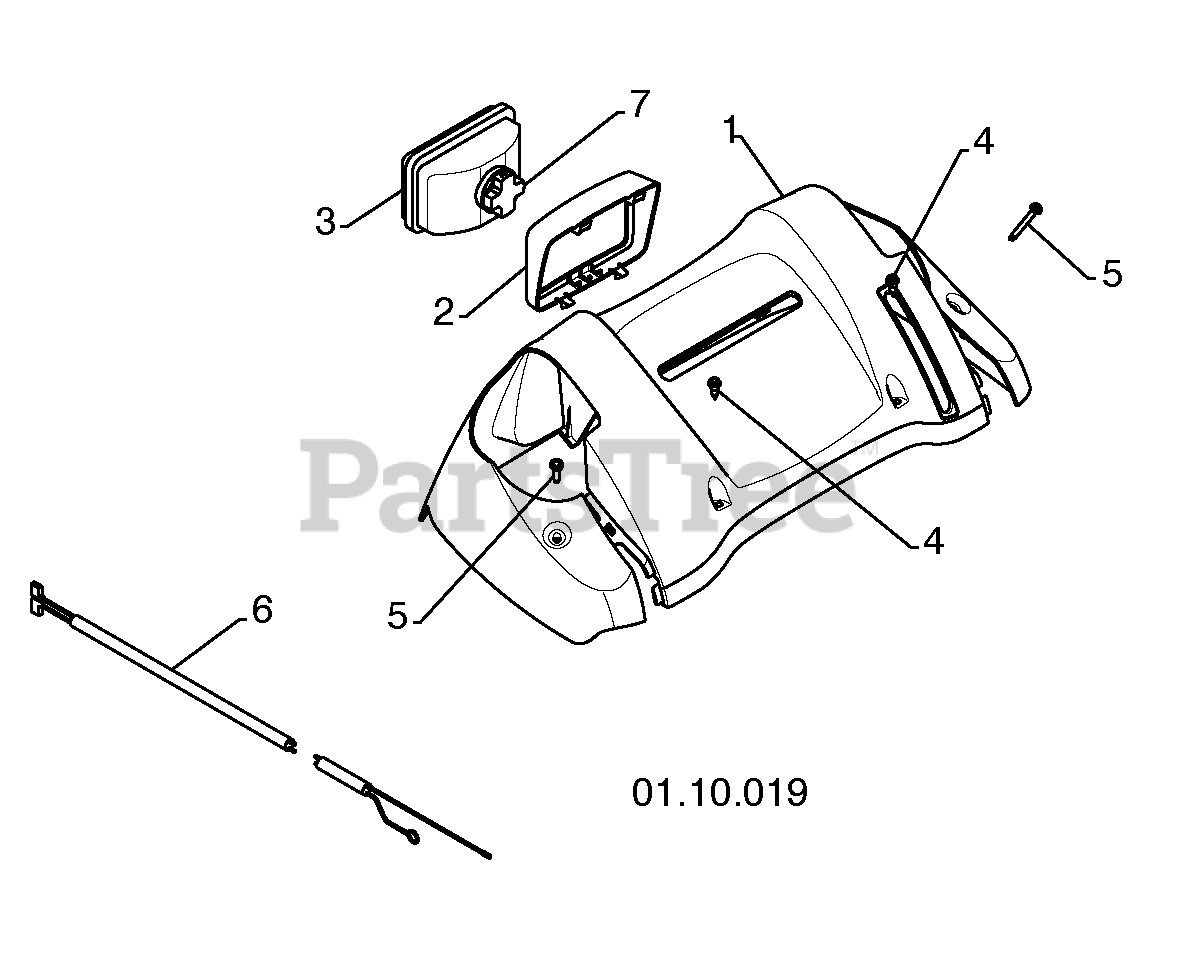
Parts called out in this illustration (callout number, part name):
1	CONSOLE PANEL
2	HEADLIGHT BEZEL
3	FLOOD HEADLIGHT
4	SHOULDER SCREW 10-24 X .625
5	SCREW 10-24 X 1.25
6	WIRE HARNESS
7	BULB
